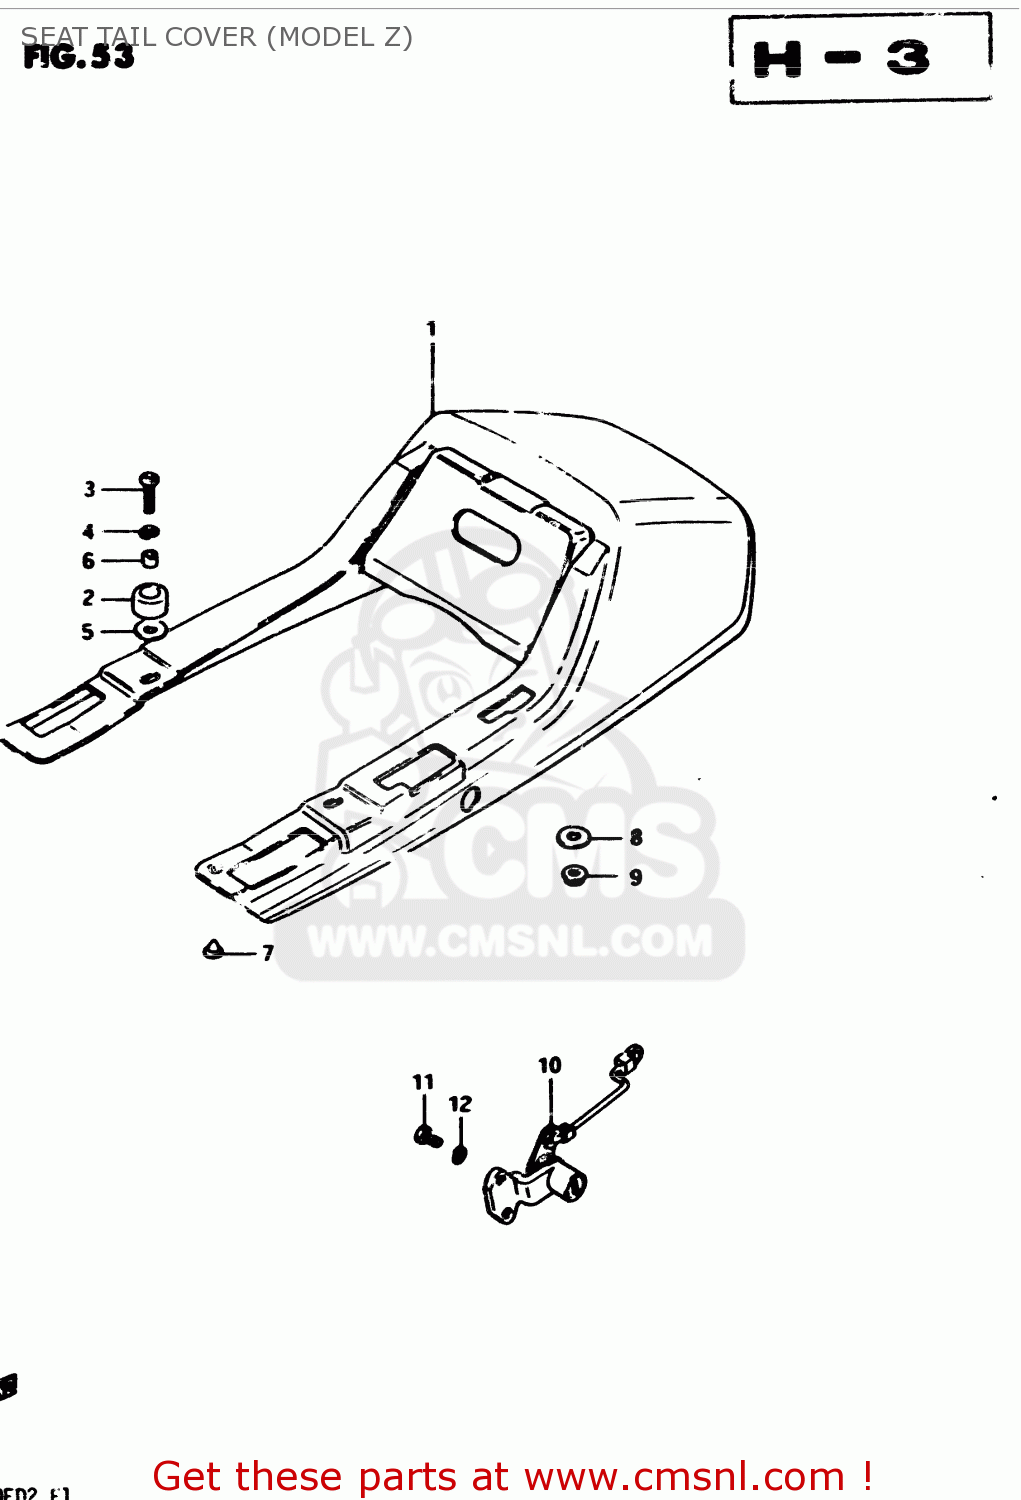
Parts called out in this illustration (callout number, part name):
1	TAIL COVER, SEAT (RED)
2	CUSHION,COVER
3	SCREW
4	LOCK WASHER
5	WASHER (6.5X24X1.6)
6	SPACER
7	CUSHION
8	WASHER
9	NUT 6MM
10	LOCK ASSEMBLY,SEAT
11	BOLT 5X10
12	LOCK WASHER
